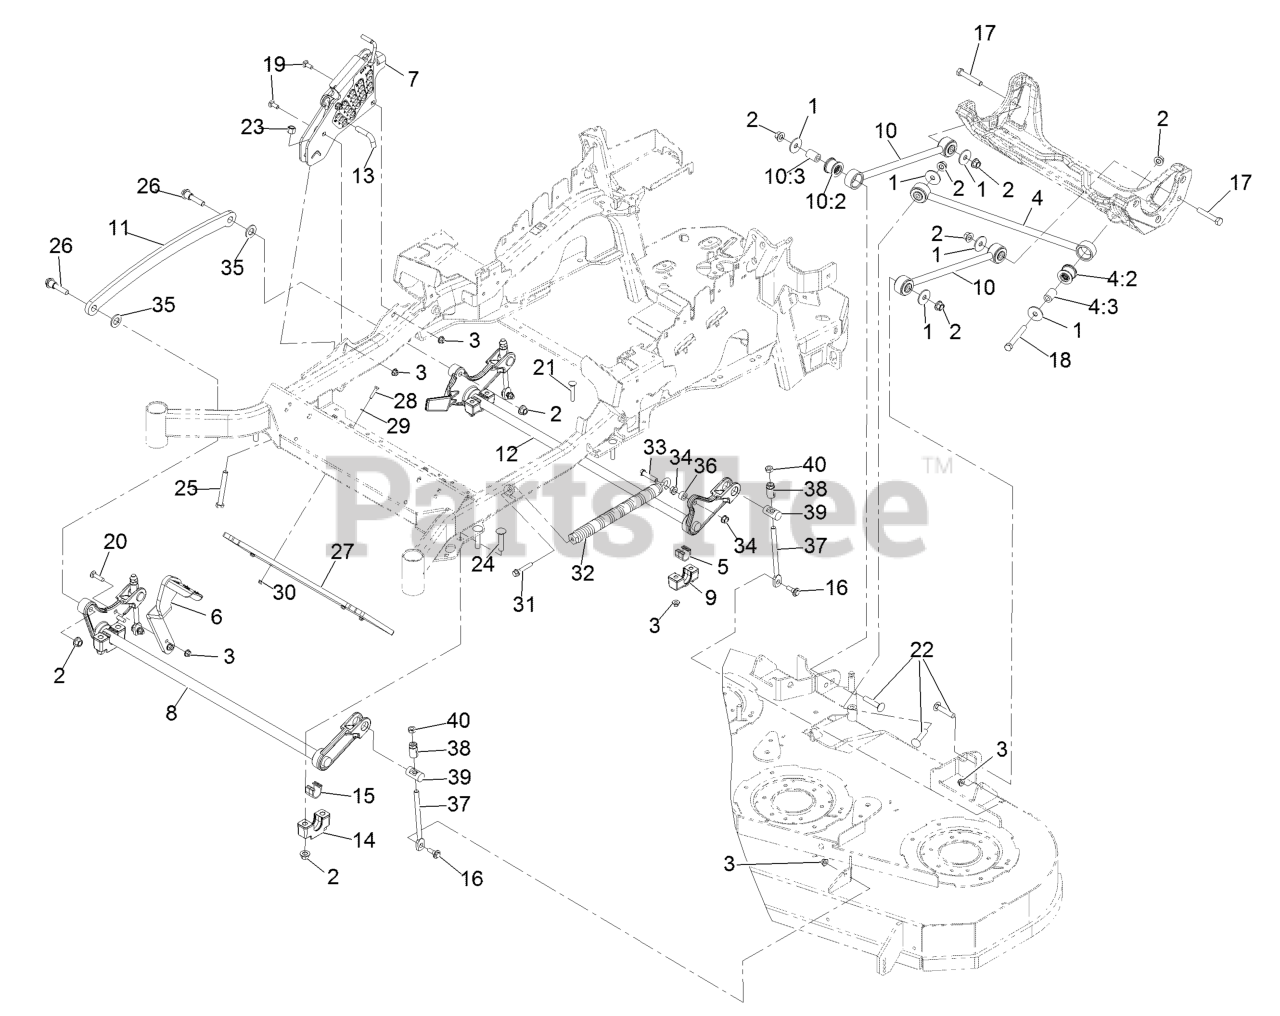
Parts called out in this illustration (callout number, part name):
1	WASHER-THRUST
2	Nut-Lock 1/2-13
3	NUT-HF, NI
4	PANHARD ROD ASM
4:2	BUSHING-SUSPENSION, RUBBER
5	BEARING-CROSS SHAFT, REAR
6	LEVER-FOOT
7	HOC ASM
8	DECKLIFT-FRONT
9	SUPPORT-CROSS SHAFT, BEARING REAR
10	DECK STRUT ASM
10:2	BUSHING-SUSPENSION, RUBBER
11	LINK-LIFT, DECK
12	LIFT-DECK, REAR
13	PIN-HOC
14	SUPPORT-CROSS SHAFT, BEARING
15	BEARING-CROSS SHAFT, FRON
16	SCREW-SHOULDER, HHF
17	SCREW-HH
18	SCREW-HH
19	BOLT-CARR
20	SCREW-CARR
21	Bolt-Carriage 3/8-16 X 2 1/4
22	SCREW-CARR
23	NUT-LOCK, NI
24	Bolt-Carriage 1/2-13 X 2 1/2 Spl Neck
25	BOLT-TAP
26	SCREW-HHF, SHOULDER
27	WEIGHT-TOE BOARD
28	SCREW-HH
29	WASHER-FLAT
31	BOLT-SHOULDER
32	SPRING-EXTENSION
33	SCREW-HH
35	WASHER-FLAT
37	LINK-ADJUSTER, DECK LIFT
38	ADJUSTER-LIFT, DECK
39	TRUNNION
40	NUT-JAM
